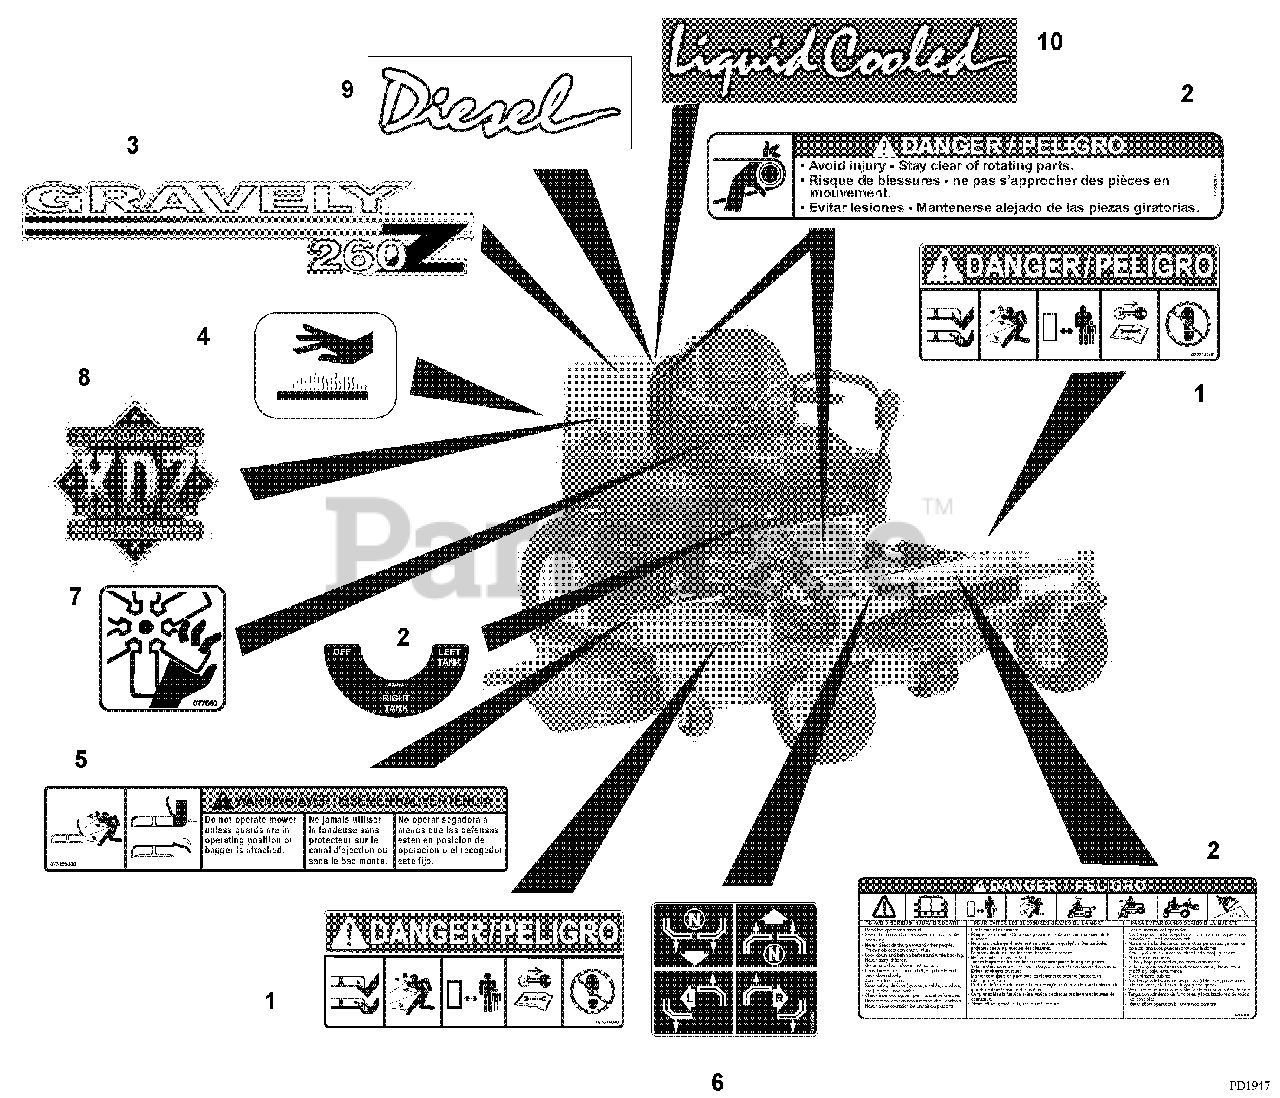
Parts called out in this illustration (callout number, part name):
1	Decal, Mower Pan Head Danger
2	Set, Decal-Common Danger/Fuel
3	Decal, PM-260Z Hood (992156)
4	Decal, Hot Surface
5	Decal, Warning
6	Decal, Instructional
7	Decal, Danger Fan
8	Decal, XDZ
9	Decal, Diesel (992156)
10	Decal, Liquid Cooled
